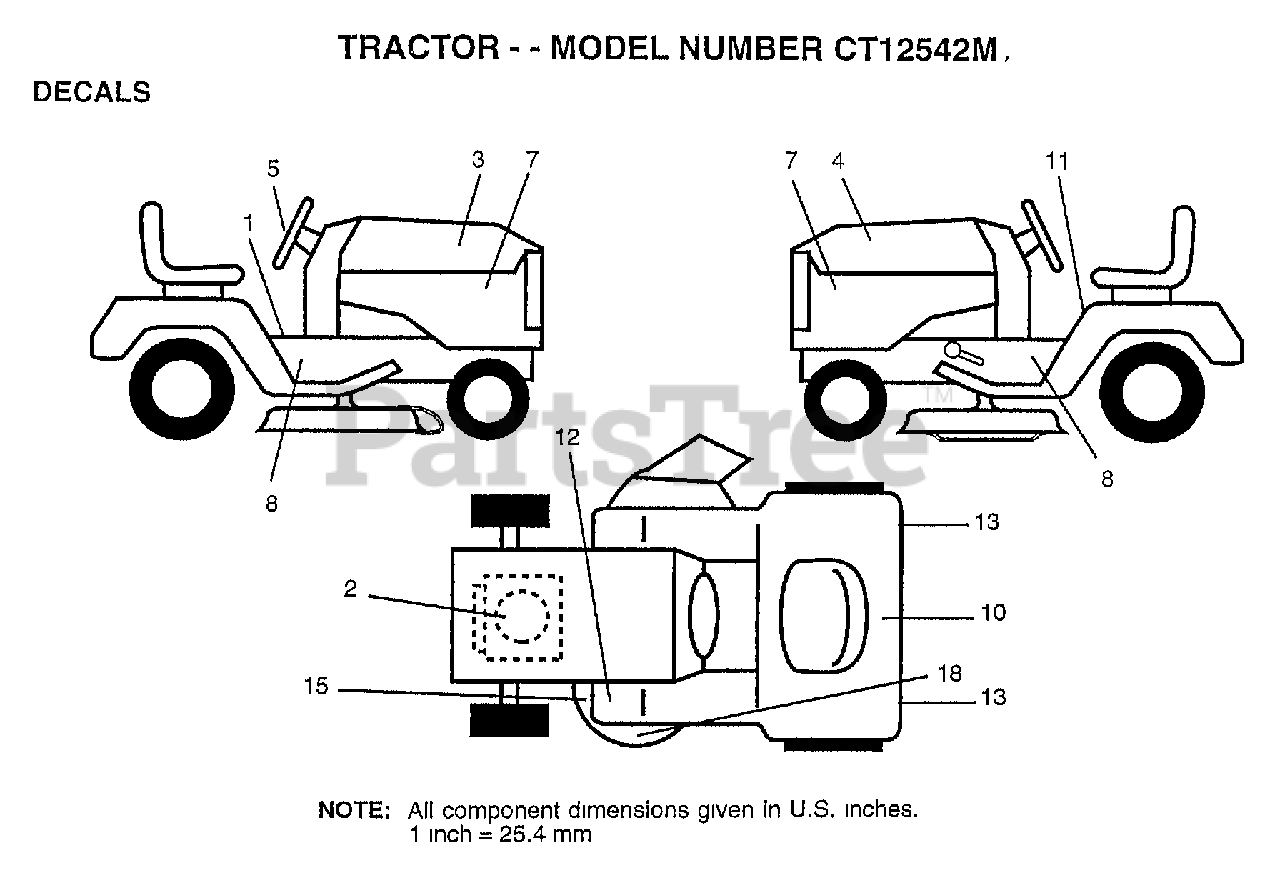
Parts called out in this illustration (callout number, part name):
1	"DECAL DASH,OPER."
2	DECAL, HP ENGINE
3	DECAL HOOD RH
4	"DECAL HOOD,LH"
5	DECAL INST STG WH
7	"DECAL PANEL,SIDE"
8	"DECAL CHASSIS 42"""
10	DECAL.BATRY.3-3908
11	"DECAL DANGER,FEND"
13	REFLECTOR-TAIL YT
15	DECAL
